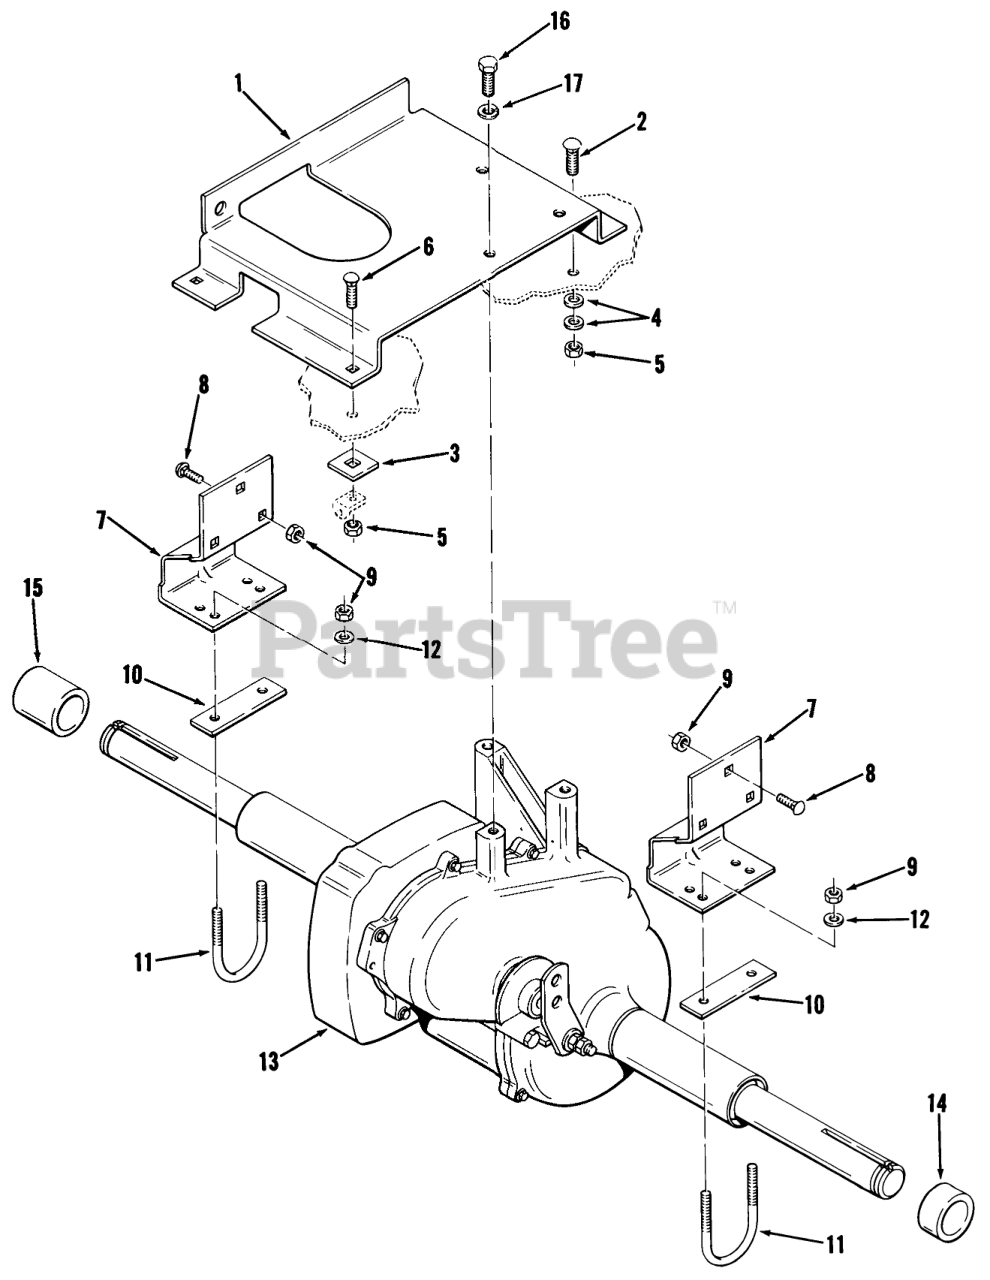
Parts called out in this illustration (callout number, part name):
1	Differential Support
2	Bolt-Carriage
3	PAD-SHORT R
4	WASHER 5/16 SAE
5	Nut
6	Bolt-Carriage
7	Bracket
8	CARRIAGE BOLT -4
9	Nut
10	Spacer
11	U-BOLT AXLE MTG
12	WASHER 5/16 SAE
13	Sleeve
14	SPACER-AXLE LH
15	Axle Spacer RH
16	BOLT
17	LOCKWASHER
